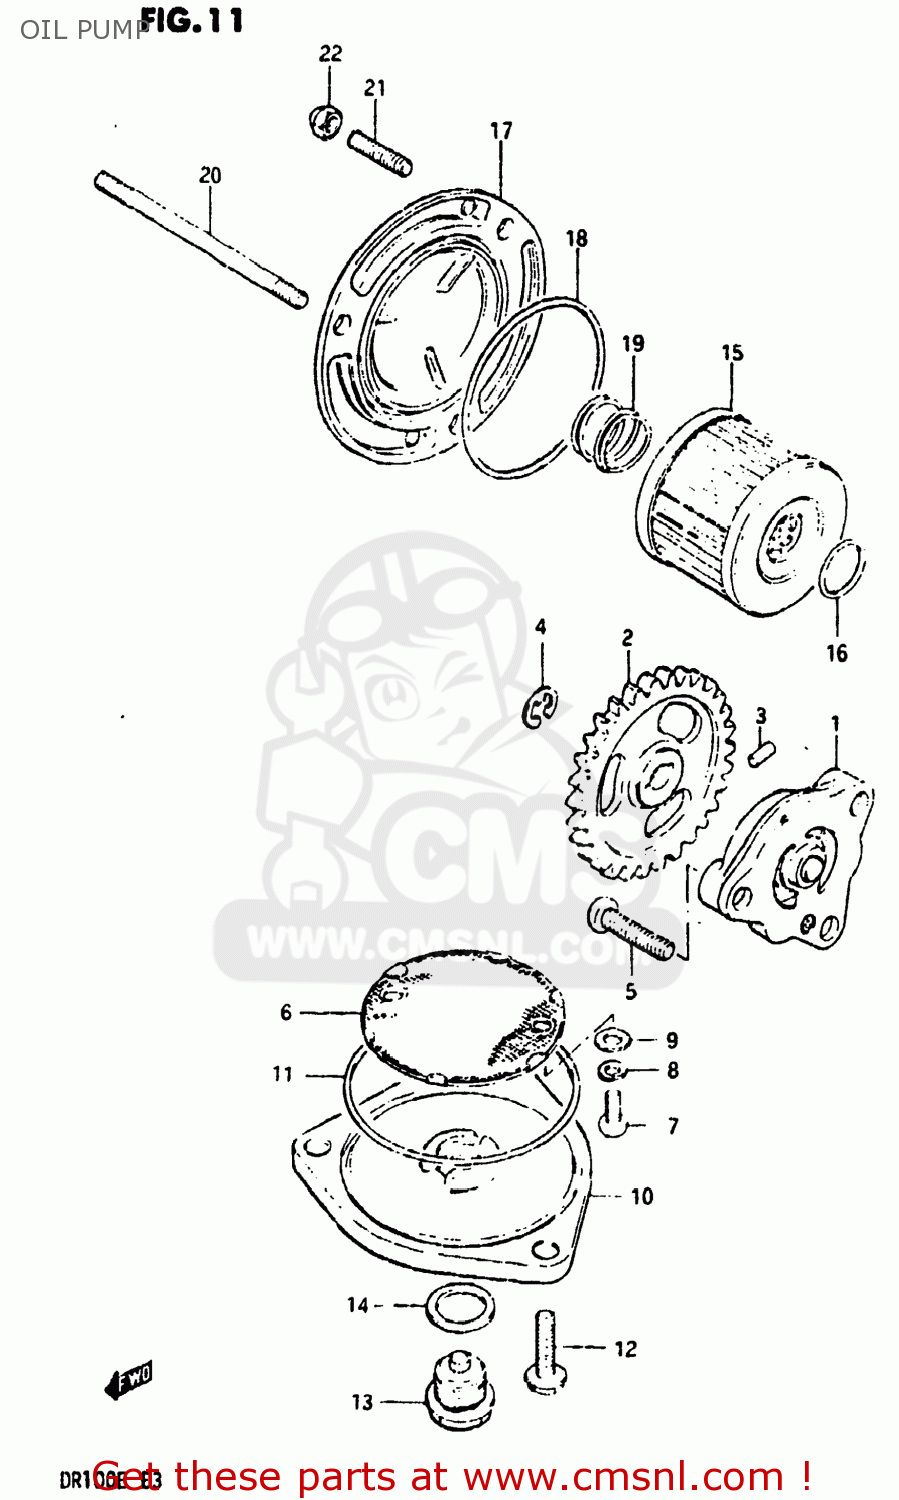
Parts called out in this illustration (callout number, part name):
1	PUMP ASSEMBLY,OIL
2	GEAR,ENG OIL PUMP DRIVEN(NT:30
3	PIN(2.5X11.8)
4	WASHER 6MM
5	SCREW
6	STRAINER,ENGINE OIL
7	SCREW
8	LOCK WASHER
9	WASHER
10	CAP,OIL STRAINER
11	O RING(D:2.4,ID:60.5)
12	BOLT,REAR
13	PLUG
14	GASKET(14X19.2X2) (NAS)
15	FILTER ASSY,ENGINE OIL
16	O RING(D:1.9,ID:13)
17	CAP,OIL FILTER
18	O RING(D:2.4,ID:52.6)
19	SPRING
20	STUD BOLT, 6X8
21	STUD 6X12
22	NUT 6MM
